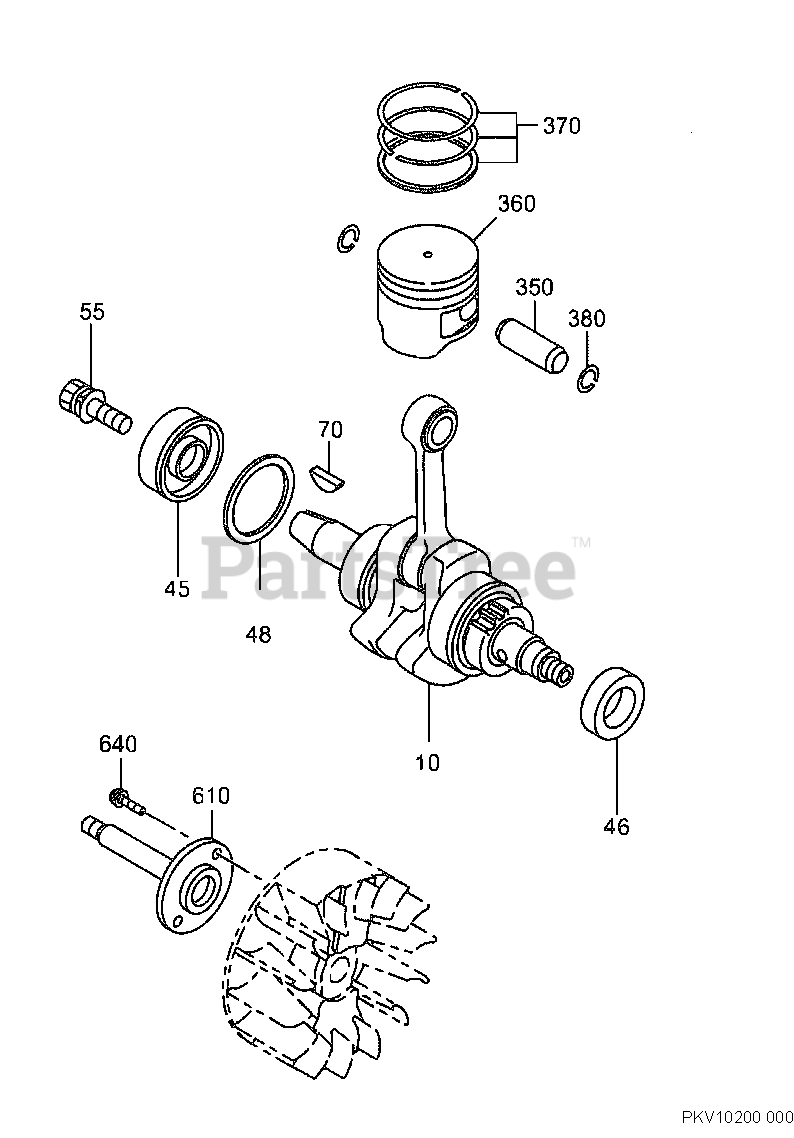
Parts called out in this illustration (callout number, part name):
10	CRANKSHAFT CP
45	OIL SEAL, LARGE
46	OIL SEAL, SMALL
55	BOLT AND WASHER
370	PISTON RING SET
640	SCREW AND WASHER AY
